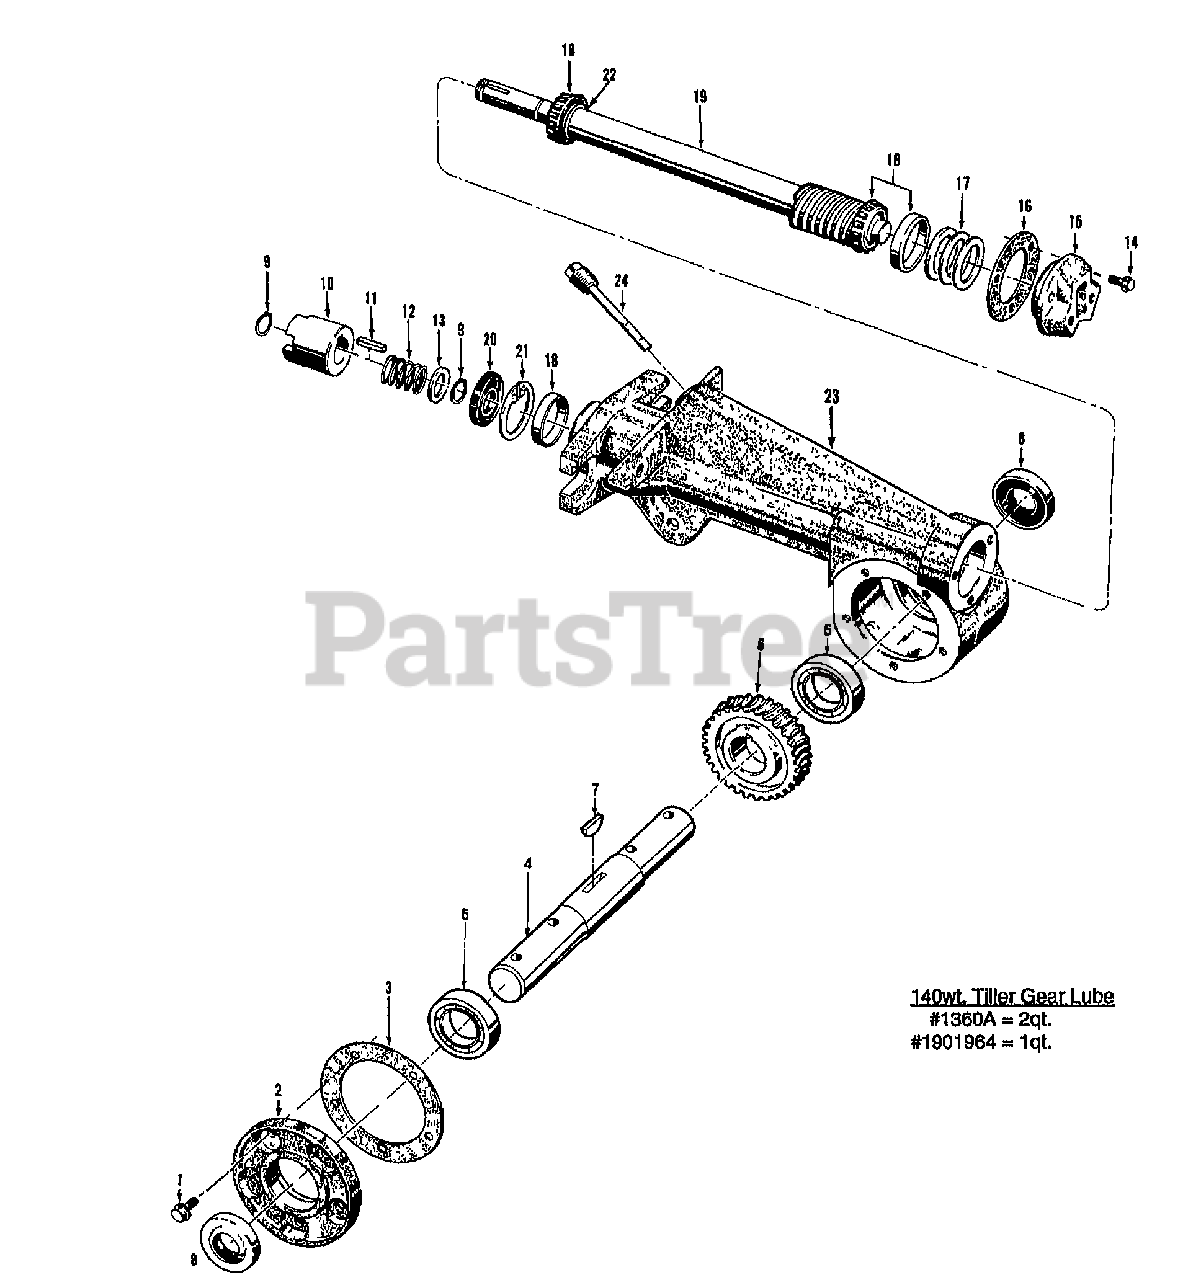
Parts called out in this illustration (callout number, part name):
1	KIT-SEALING SCRS (5)W/LIT
2	COVER-TILLER HSG MACH
3	GASKET-TILLER COVER
4	SHAFT-TILLER MACH HORSE
5	BEARING-BALL
6	GEAR-WORM MACH RTH HORSE
7	KEY-WOODRUFF .25X1.12
8	SEAL-TILLER SHAFT
9	RING-RETAIN EXT .707 ID
10	KIT-CLUTCH DOGS TILLER
10	CLUTCH-DOG HORSE TRANS
11	KEY-.188 SQX1.0
12	SPRING (TC)
13	SHIM-1.0X.7656X.062
14	KIT-SEALING SCRS (3)
15	CAP-REAR #1115
16	GASKET-BRG COVER
17	SHIM-1.75X1.5X.01
17	SHIM-1.75X1.5X.03
17	SHIM-1.75X1.5X.005
17	SHIM-1.75X1.5X.062
18	KIT-BRG CONE&RACE-DRIVESHAFT
19	KIT-TILLER DR SHAFT
20	SEAL-OIL DRIVESHAFT
21	RING-RETAINING 5000-181
22	SHIM-1.0X.7656X.062
23	HOUSING-TILLER W/SLEEVE
24	ASSM-DIPSTICK HORSE TRANS
